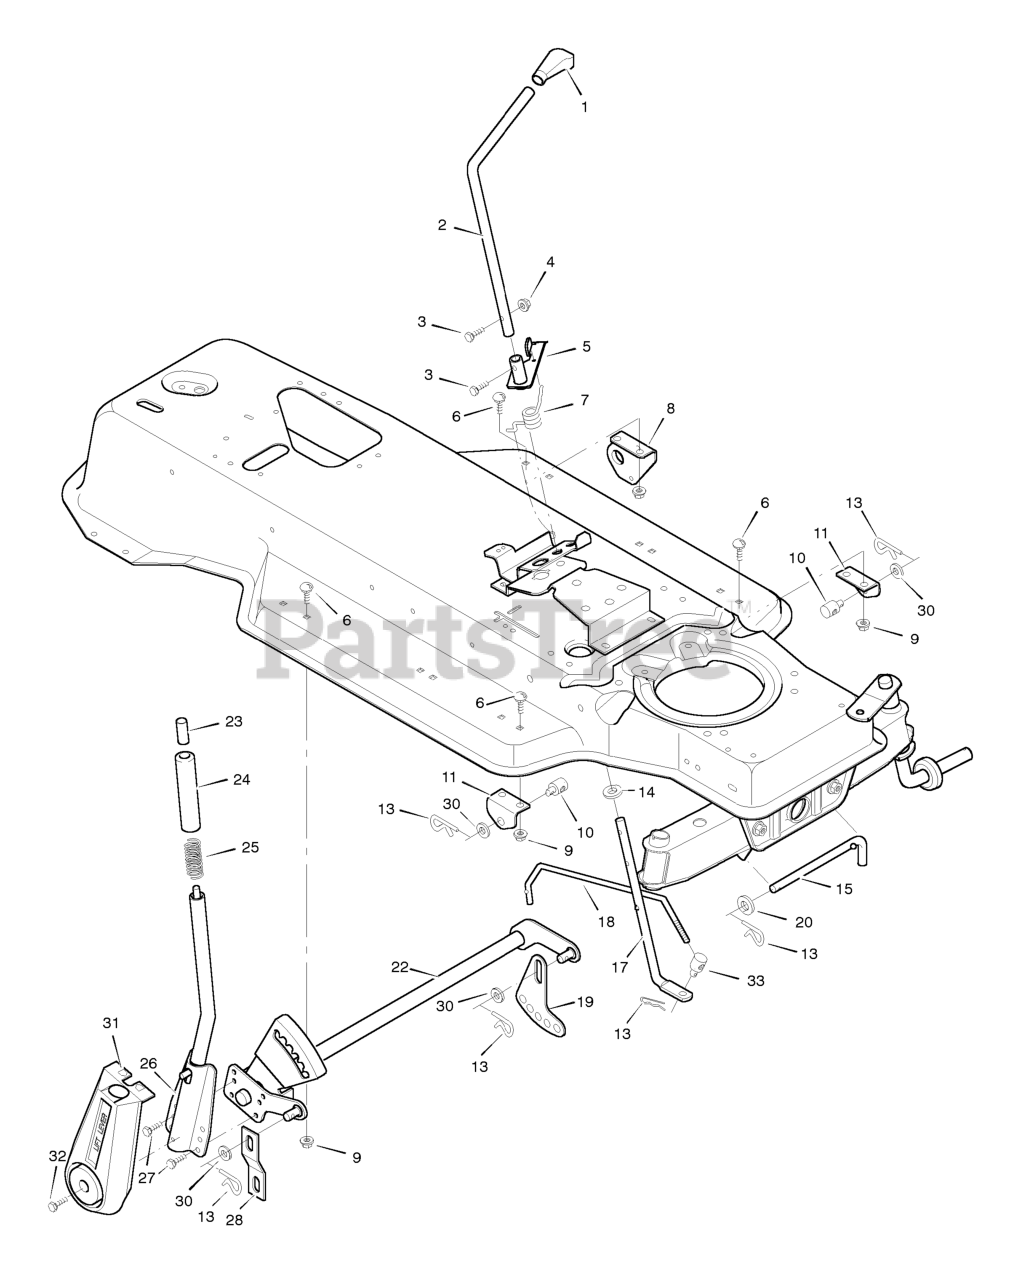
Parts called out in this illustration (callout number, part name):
1	Grip
2	Control, Blade Rotation
3	Screw, Hex
4	Locknut, Hex
5	Lever Assembly, Switch
6	Bolt, Carriage
7	Spring, Torsion
8	Bracket, Rear Hanger
9	Nut, Flange
10	Nut, Adjusting
11	Bracket, Adjuster Rod
13	Pin, Hair
14	Washer
15	Pin, Pull
17	Lever, Lower Blade Control
18	Rod, Blade Control
22	Lifter Assembly
23	Button, Push
25	Spring, Compression
26	Handle Assembly
31	Cover, Lift Lever
33	Nut, Adjusting
